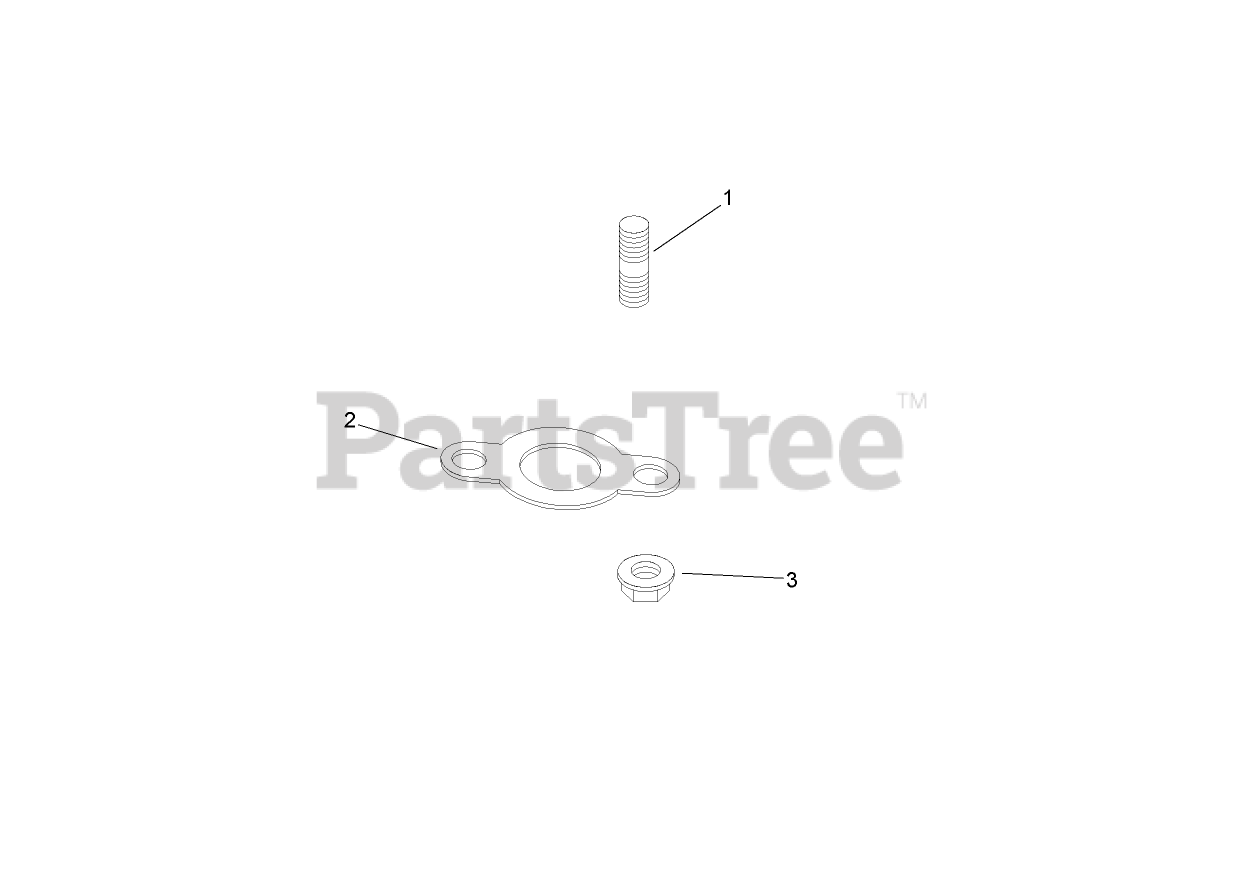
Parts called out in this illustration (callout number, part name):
1	STUD (M8X1.25X33)
2	GASKET-EXHAUST
3	NUT-FLANGE (M8X1.25)
